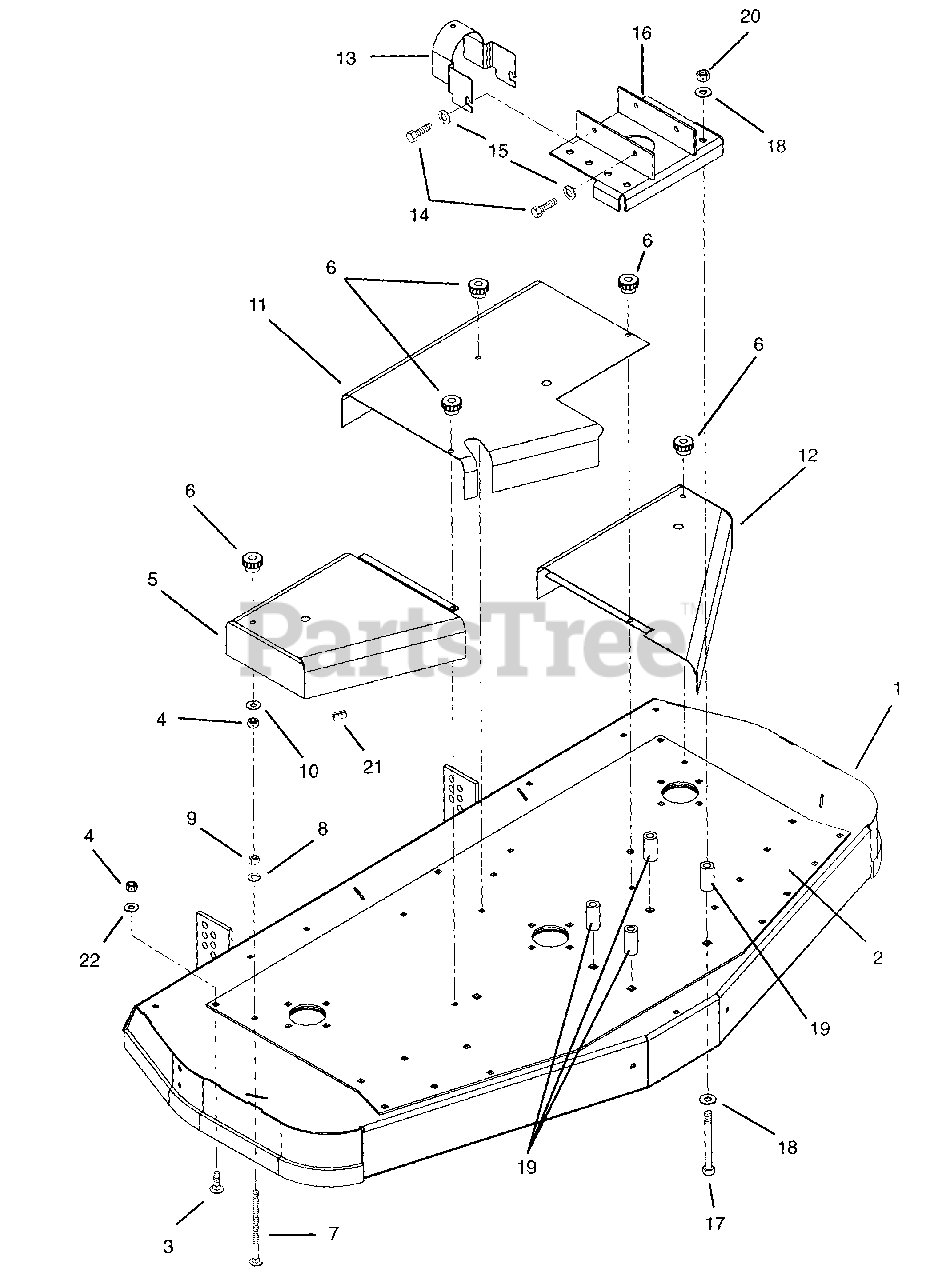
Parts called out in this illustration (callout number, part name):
1	Weldment, 60" Rear Discharge
2	Plate, Reinforcing 60" Deck
3	Bolt-Round Head Square Neck .38-16 x .75 Grade 5
4	Nut-Locking-Center .38-16
5	Cover, Belt Right Hand 60"
6	Knob
7	Bolt-Round Head Square Neck .312-18 x 4.0
8	Washer-Locking .31 x .078
9	Nut-Hex .31-18
10	Washer-Flat-Steel .38 x .875 x .083
11	Cover, Belt Middle 60"
12	Cover, Belt Left Hand 60"
13	Shield, U-Joint
14	Bolt-Hex .38-16 x 1.00 Grade 5
15	Washer-Lock .38 x .094
16	Weldment, Gearbox
17	Bolt-Hex .50-13 x 3.50 Grade 5
18	Washer-Flat-Steel .531 x 1.06 x .095
19	Spacer .562 x 1.00 x 2.00
20	Nut-Locking-Center .50-13
21	Trim Bumper
22	Washer-Flat-Steel .406 x .812 x .065
